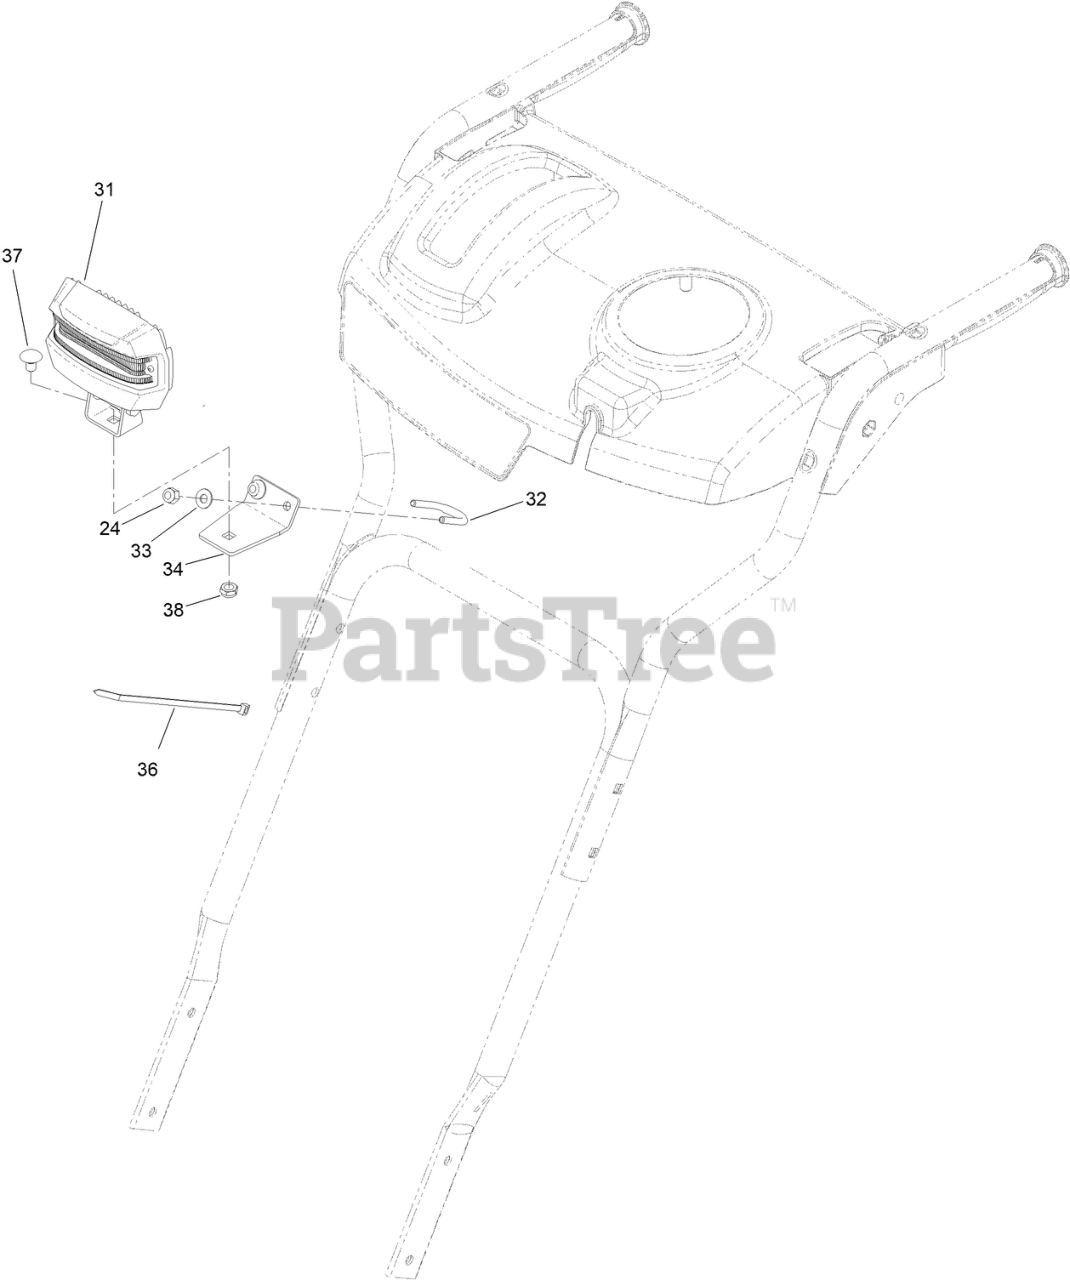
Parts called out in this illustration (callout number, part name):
24	NUT-HEX
31	LED LIGHT ASM
32	CLAMP-LIGHT
33	WASHER-PLAIN
34	BRACKET-LIGHT
36	TIE-CABLE
37	BOLT-CARR
38	NUT-HEX
